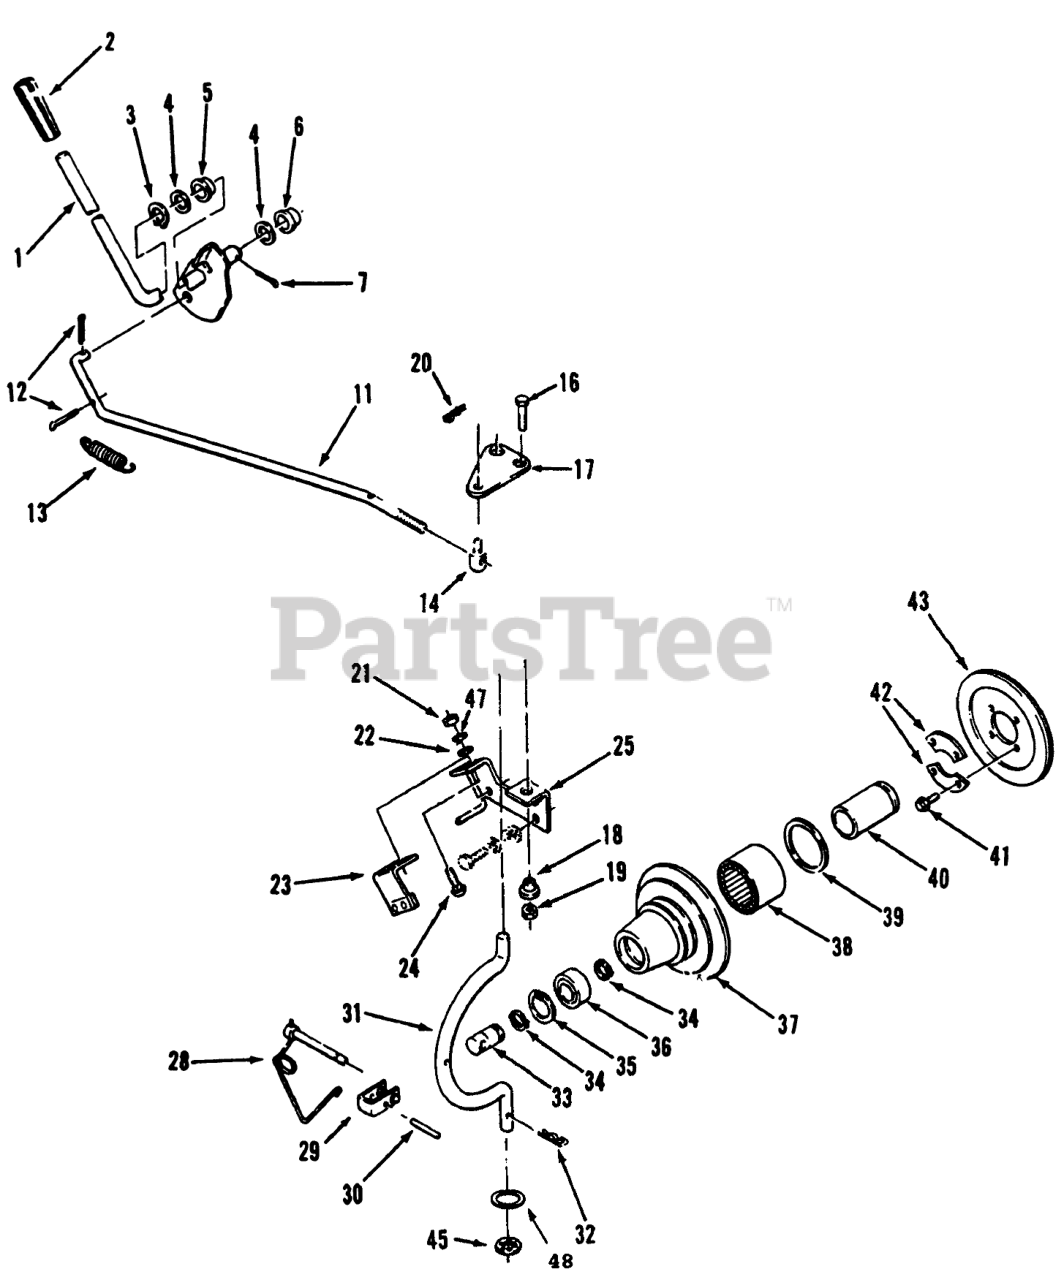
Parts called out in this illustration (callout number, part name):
1	Lever-Clutch,PTO
2	GRIP
3	RING-EXT GRIP
4	SHIM-WASHER
5	BUSHING-NYLINER
6	NYLINER BUSHING
7	PIN-COTTER
11	ROD-PTO CLUTCH
12	PIN-COTTER
13	SPRING
14	TRUNNION
16	SCREW-HH
17	PLATE
18	SPACER-LIFT LINK
19	NUT-LOCK, NI
20	Hairpin Cotter
21	NUT-HEX
22	WASHER-FLAT
23	ASM-Bracket
24	SCREW-CARR
25	Bracket-Engine
28	LOCKING PIN ASM
29	CLEVIS
31	ROD-HOUSING
32	Hairpin
33	SHAFT-PTO
34	Ring-Snap
35	RING-RETAINING
36	BEARING-BALL
37	Housing-Clutch
38	Seal
39	BRG-NEEDLE OPEN END
40	RACE-BEARING
41	H H C S
42	RETAINER
43	Facing-Clutch
45	RING-REINFORCED CIRC
47	WASHER-LOCK
48	Washer-Flat
